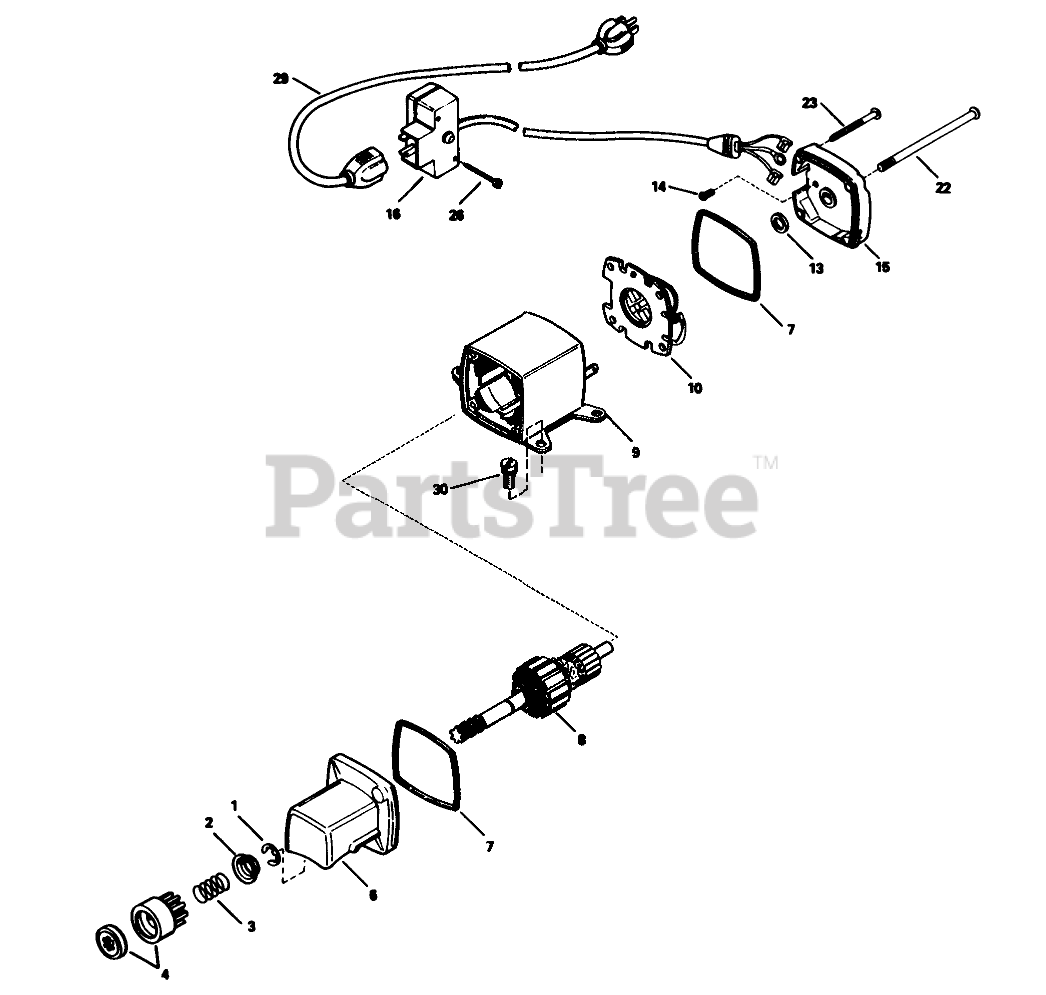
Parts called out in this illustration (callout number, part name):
1	Retainer-Ring
2	Retainer-Spring
3	Spring-Anti Drift
4	Nut & Gear
6	Cap Assy.-Drive End (Incl. Ref. #7)
8	Armature
9	Housing Assembly
10	Card ASM
13	Washer-Thrust
14	Screw-Ground
15	Cap Assy.-Commutator End (Incl. Ref. #7)
16	Switch Box ASM
22	Bolt-Case
23	Screw-Ground
29	Cord-Extension
30	Screw (T-30, 1/4-20 x 23/32)
